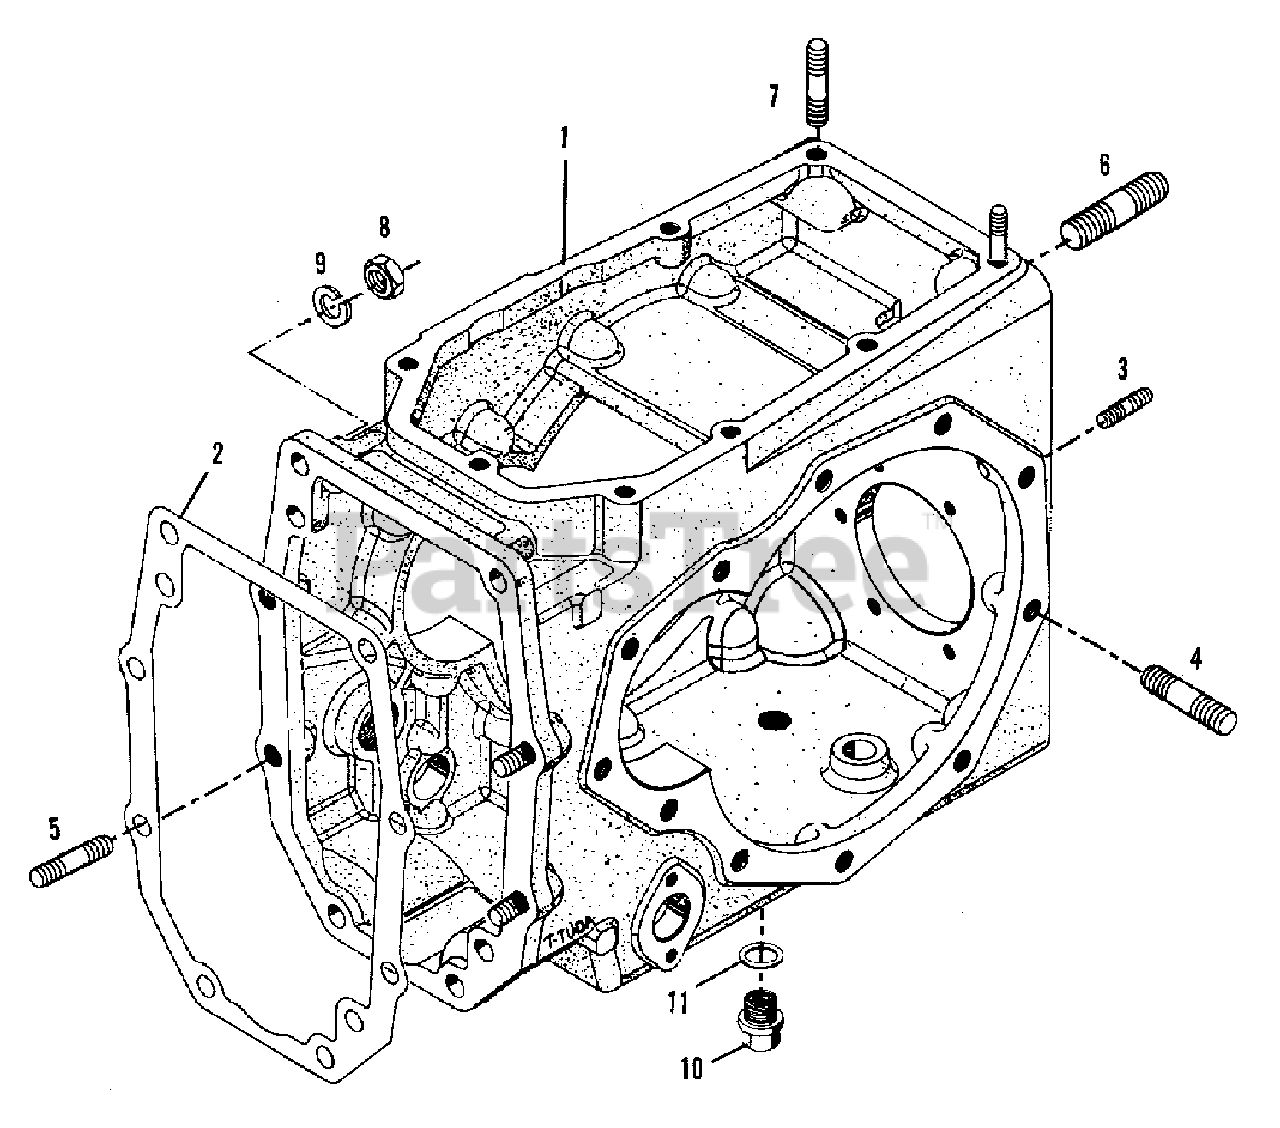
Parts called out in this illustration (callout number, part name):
1	HOUSING ASSEMBLY, rear (Incl. Items 3 thru 7)
2	GASKET, front
3	STUD, M8 x 18 (Seal lock No. 10)
4	STUD, M12 x 40
5	STUD, M12 x 28
6	STUD, M16 x 29
7	STUD, M10 x 50
9	LOCKWASHER, M12
10	PLUG, drain
11	GASKET, drain plug
